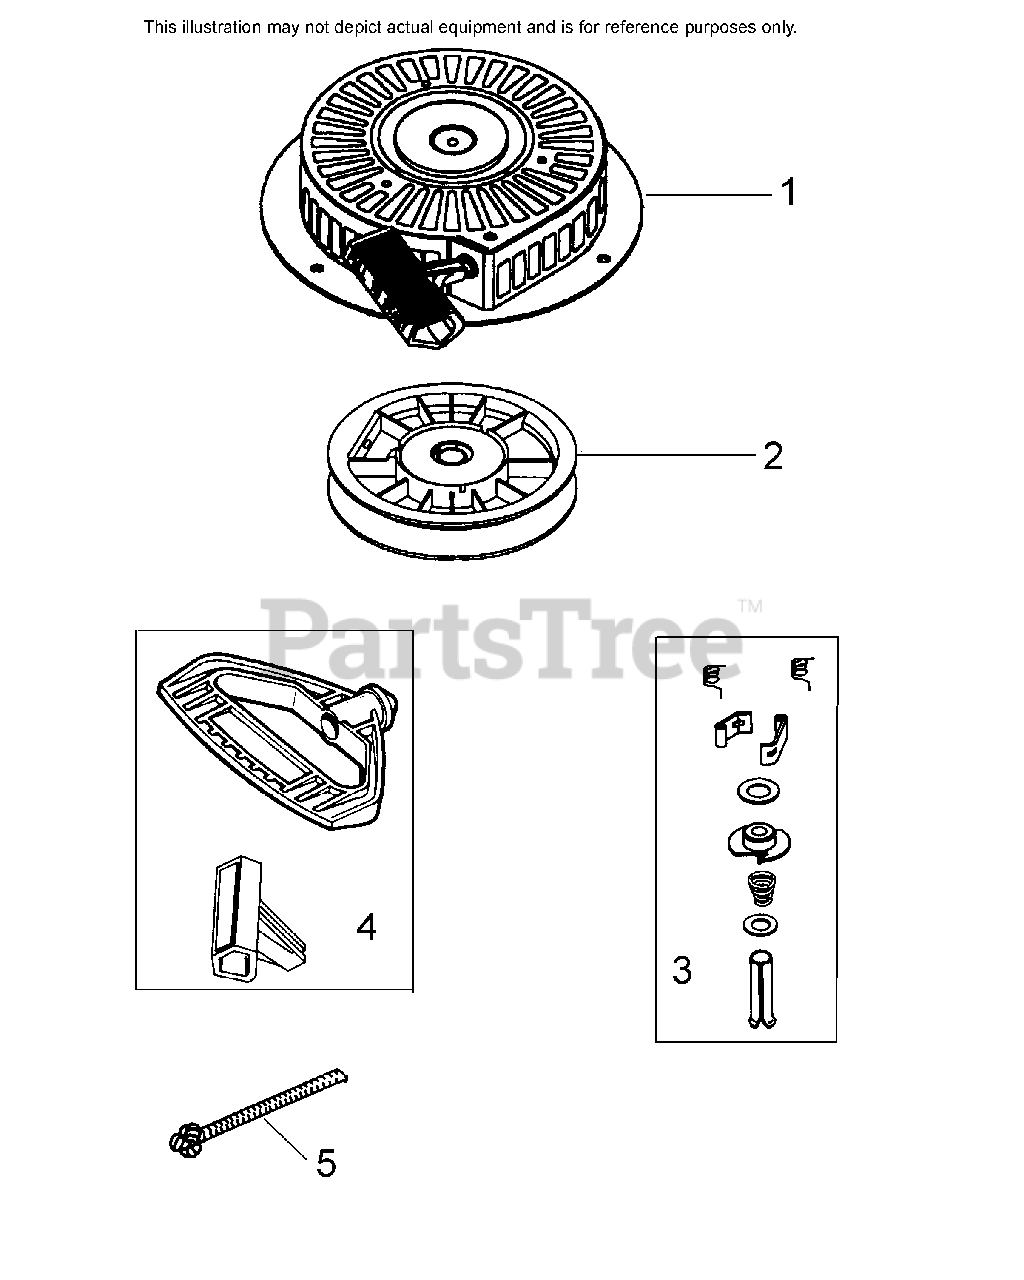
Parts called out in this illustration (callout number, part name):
1	"Recoil Starter
2	Pulley & Rewind Spring Assembly
3	Recoil Repair Kit (does not incl. pul ley, rope, or housing)
4	Starter Handle (Standard) also availa ble in 740033B Starter Rope & Handle Kit
5	98" Starter Rope (cut to length) also available in 740033B Starter Rope & Handle Kit
